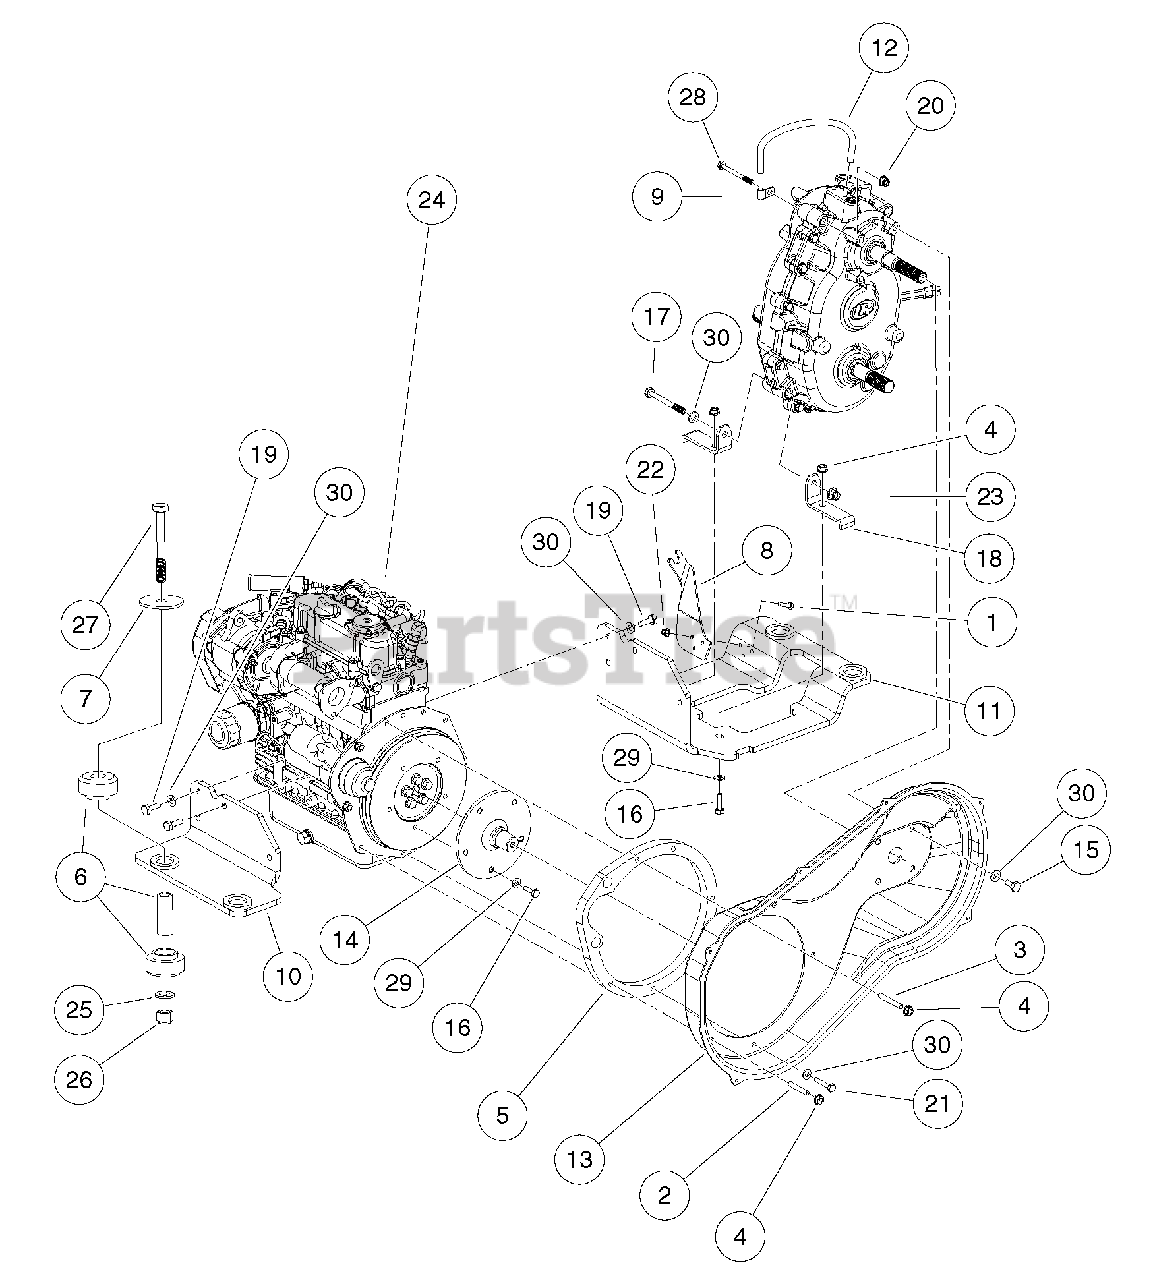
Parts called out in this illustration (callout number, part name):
1	Screw, M6-1.00 X 25mm Hex Cap
2	Stud, M8-1.25 X 50 mm Two-Ended
3	Stud, M8-1.25 X 60mm Two-Ended
4	Nut,m8,all Metal Lock
5	Spacer, Engine, Diesel
6	Isolator Ring and Bushing
7	Washer, Snubbing, Ring N Bush
8	Bracket, FNR Trans Cable
9	P-Clamp, Insulated .312 In
10	Plate, Engine Mounting, Weld, Left-Hand
11	Plate, Engine Mounting, Weld, Right-Hand
12	Hose, Vent, Transmission
13	Cover, CVT Inner, Diesel
14	Shaft, CVT Adapter
15	Bolt, M10 X 1.5 X 20 Loctite
16	Bolt, M8 X 1.25 X 25 Loctite
17	Bolt, M10 X 1.5 X 100 Loctite
18	Bracket, Transmission Mounting
19	Bolt, M10 X 1.25 X 25 Loctite
20	Lock Nut, Flg M8 X 1.25 Nylon
21	Bolt, M8 X 1.25 X 40 with Loctite
22	Nut Flg, M6 X 1.0 Nylon
23	Nut Flg M10 X 1.5 Nylon
24	Engine, Kubota, D722, with Closed Breather, 60a
25	Washer, M12 Hard
26	Locknut, M12x1.75 Nylon Insert
27	Bolt, M12 X 1.75 X 90
28	Bolt, M8 X 1.25 X 80
29	Washer, M8 Hard
30	Washer, M10 Hard
